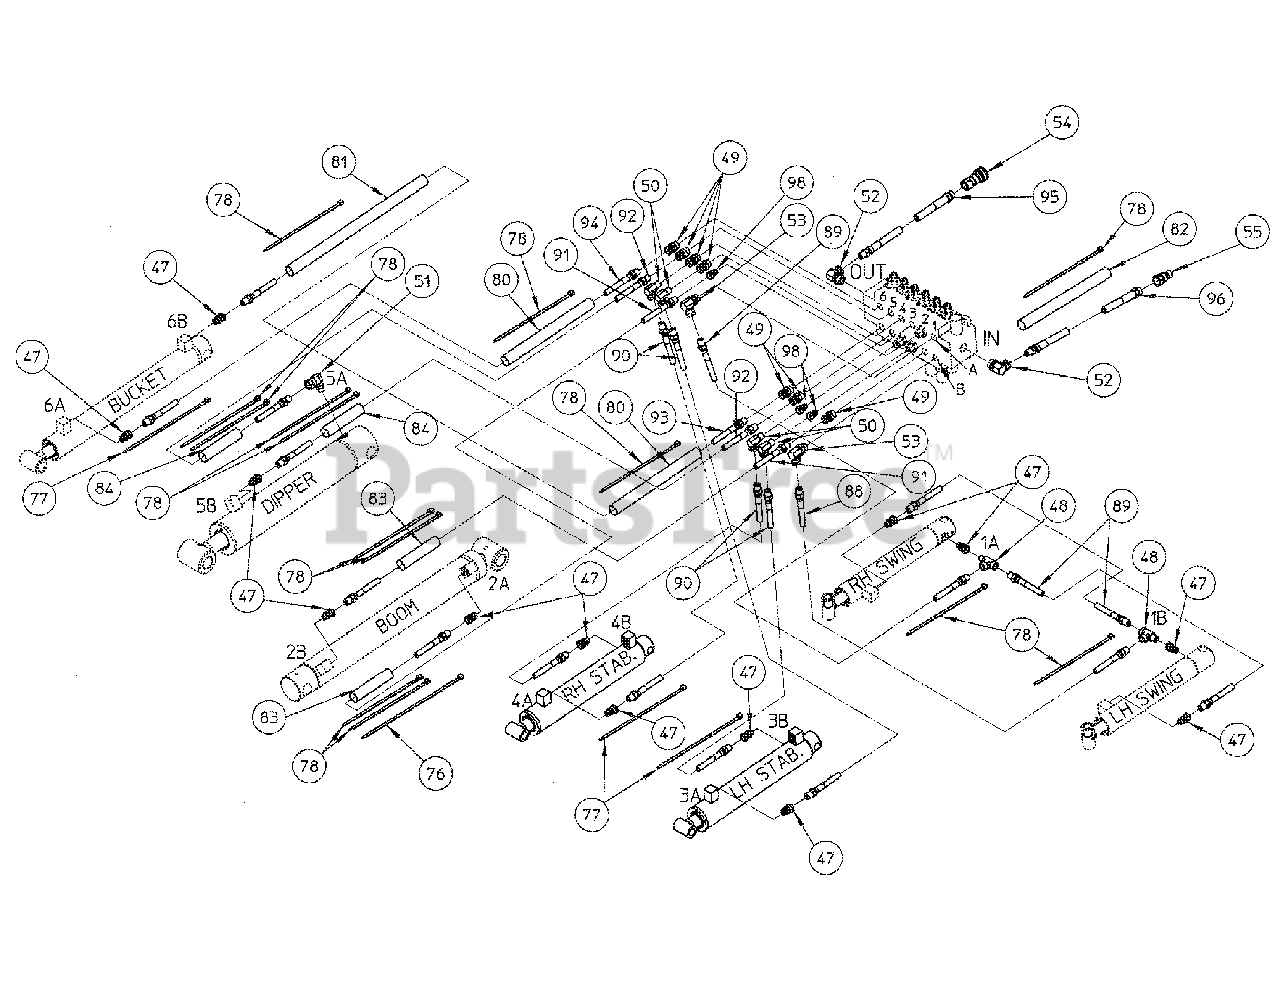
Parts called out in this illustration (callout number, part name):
1	Hydraulic Cylinder - Swing
2	Hydraulic Cylinder - Bucket
3	Hydraulic Cylinder - Stabilizer
4	Hydraulic Cylinder - Boom
5	Hydraulic Cylinder - Dipper
6	Bolt, Carriage 5/16 NC x 3/4"
7	Bolt, Carriage 5/16 NC x 1-1/4"
8	Bolt, 1/4 NC x 3/4"
9	Bolt, 5/16 NC x 3/4"
10	Bolt, 5/16 NC x 3/4" Thread Forming
11	Bolt, 5/16 NF x 3/4"
12	Bolt, 5/16 NF x 7/8"
13	Bolt, 5/16 NF x 1" Gr. 5
14	Bolt, 5/16 NF x 2-1/4" Gr. 5
15	Bolt, 5/16 NF x 2-1/2" Gr.5
16	Bolt, 5/16 NF x 4" Gr. 8
17	Bolt, 3/8 NF x 3/4"
18	Bolt, 3/8 NF x 1"
19	Bolt, 3/8 NF x 1-1/4"
20	Bolt, 3/8 NF x 1-3/4"
21	Bolt, 3/8 NF x 2-1/4"
22	Bolt, 3/8 NF x 2-3/4"
23	Bolt, 3/8 NC x 5-1/2" Long Gr.5
24	Bolt, 1/2 NF x 7/8"
25	Nut, 1/4 NC
26	Nut, 5/16NC
27	Locknut, 5/16 NC
28	Nut, 5/16 NF
29	Locknut, 5/16 NF
30	Lock Nut, 3/8NC
31	Locknut, 3/8 NF
32	Lockwasher, 1/4
33	Lockwasher, 5/16
34	Flat Washer. 5/16 STD
35	Washer, 5/16 SAE
36	Flat Washer, 3/8 SAE
37	Flat Washer, 1/2" Hardened
38	Machine Bushing, 1-1/4 OD x 3/4 ID x 14Ga.
39	Machine Bushing 1-1/2" OD x 1" ID x 18Ga.
40	Machine Bushing 1-7/8" OD x 1-1/4" ID x 18Ga.
41	Machine Bushing, 2-1/2 OD x 1-3/4ID x 18Ga
42	Cotter Pin, 3/32" Dia x 3/4"
43	Cotter Pin, 3/16 x 1-1/4"
44	Cotter Pin, 1/4 x 1-1/2"
45	Hair Pin Cotter, 3/64" Dia x 11/16"
47	Adapter Union, 9/16-18M x 3/8NPTF
48	Hydraulic Tee
49	Adapter Union, 3/4-16M x 3/8NPTF x Straight
50	Adapter Union, 3/8NPTM x 3/8NPTF x 90 degree
51	Adapter Union, 9/16-18M x 3/8NPTF x 90 degree
52	Adapter Union, 7/8-14M x 3/8 NPTF x 90 degree
53	Adapter Union, 3/4-16M x 3/8NPTF x 90 degree
54	Coupler Body 3/4-16F Thread
55	Coupler Nose 3/4-16F Thread
56	Garlock Bearing, 028DXR020
57	Bronze Bearing
58	Garlock Bearing, 028DXR016
59	Stabilizer Pad Weldment
60	Guide Link
61	Bucket Link
62	Street Pad
63	Clevis Pin, 3/16" Dia x 5/8"
64	Clevis Pin, 1/4" Dia x 7/8"
65	Pin Retainer
66	Pin Retainer
67	Boom Lock Pin
68	Swing Lock Pin
69	SMV Socket
70	SMV Bracket
72	Ball Joint - Shouldered
73	Ball Joint
74	Control Knob
75	Rubber Cap
76	Plastic Tie T150L
77	Plastic Tie T120 L
78	Plastic Tie T50L
80	Hose Sleeve FC425-16 X 30" Long
81	Hose Sleeve FC425-16 X 19" Long
82	Hose Sleeve FC425-16 X 48" Long
83	Hose Sleeve FC425-16 X 63" Long
84	Hose Sleeve FC425-16 X 79" Long
85	Grease Fitting
86	Grease Fitting (Two are part of #000187 Cyl.)
87	Grease Fitting (Two are part of #000187 Cyl.)
88	Hydraulic Hose, 3/8NPTM x 3/8NPTM x 20" long
89	Hydraulic Hose, 3/8NPTM x 3/8NPTM x 23" long
90	Hydraulic Hose, 3/8NPTM x 3/8NPTM x 30" long
91	Hydraulic Hose, 3/8NPTM x 3/8NPTM x 58" long
92	Hydraulic Hose, 3/8NPTM x 3/8NPTM x 76" long
93	Hydraulic Hose, 3/8NPTM x 3/8NPTM x 92" long
94	Hydraulic Hose, 3/8NPTM x 3/8NPTM x 110" long
95	Hyd. Hose, 3/8ID 3/8NPTF M x 3/4-16 Str O x 49"
96	Hyd. Hose, 3/8ID 3/8NPTF M x 3/4-16 Str O x 34"
97	Control Valve
98	Adapter Union, 7/16-20M x 3/8NPTF
99	Rear Shroud
100	Stabilizer Lever Control Rods
101	Control Rod
102	Pivot Pin, Boom Cyl. Rod 1-1/4" Dia. x 6" Long
103	Thrust Washer
104	Pivot Pin, Bucket 1"Dia. x 7-3/8" Long
105	SMV Socket Mount
106	Stabilizer Control Lever
107	Lever Bracket
108	Hose Clamp - Short
109	Pivot Pin, 3/4" Diameter x 4-1/16" Long
110	Pivot Pin, Dipperstick 1-1/4" Dia. x 7-15/16" Long
111	Pivot Pin, Stabilizer Leg
112	Pivot Pin Weldment
113	Pivot Pin, Stabilizer Pad 3/4" Dia. x 4-15/16" Long
114	Pivot Pin, Stabilizer Cyl. Rod
115	Pivot Pin, Bucket Cyl. Base 1" Dia. x 5-7/8" Long
116	Pivot Pin, Boom Cyl. Base 1-1/4" Dia. x 7-1/4" Long
117	Lower Pivot Pin Weldment
118	Seat Plate Weldment
119	RH Pivot Weldment
120	LH Pivot Weldment
122	Stabilizer Leg Weldment
123	Upper Pivot Pin Weldment
124	Pivot Pin Weldment, Boom 1-3/4" Dia. X 2-3/4" Lg
125	RH Toe Shield
126	LH Toe Shield
127	Hose Clamp - Long
128	Grab Bar Weldment
129	Mainframe Weldment
130	Valve Mount Weldment
131	Swing Frame Weldment
132	Front Shroud Weldment with Decals
133	Dipperstick Weldment
134	Boom Weldment
135	Right Hand Joystick Weldment
136	Left Hand Joystick Weldment
